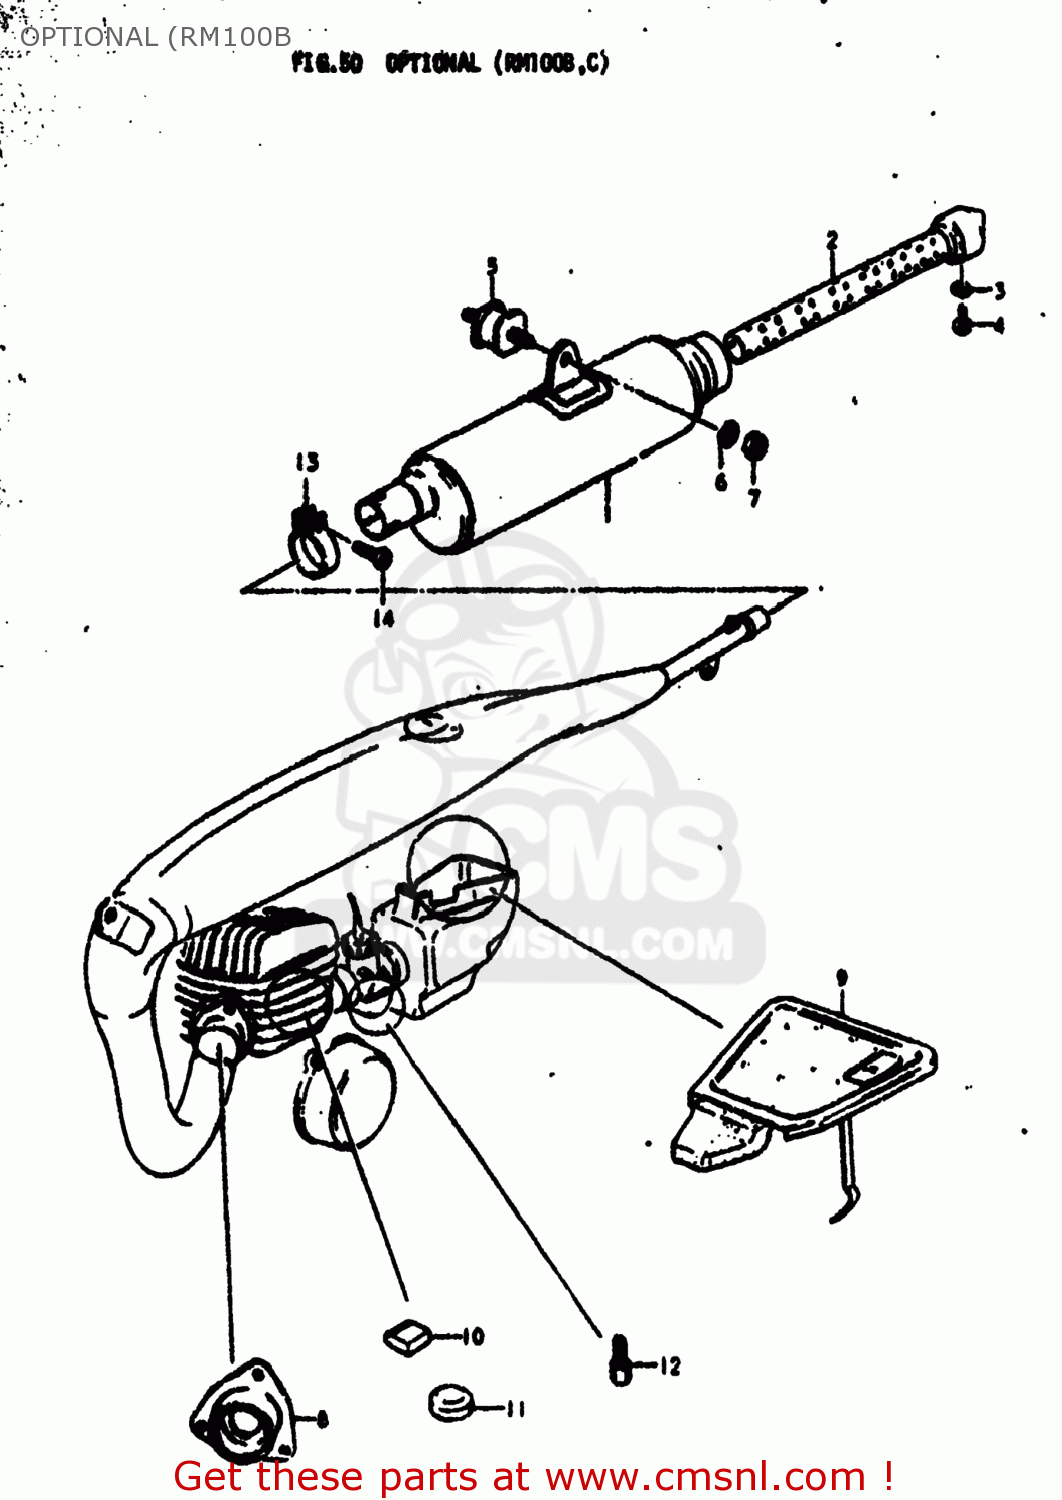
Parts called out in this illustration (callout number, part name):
0	OFF-ROAD SOUND KIT
1	MUFFLER ASSEMBLY
2	PIPE,MUFFLER BAFFLE
3	LOCK WASHER
4	SCREW
5	DAMPER,MUFFLER SUPPORT
6	LOCK WASHER
7	NUT
8	FLANGE,EXHAUST PIPE
9	CAP,AIR CLEANER
10	PAD,CYLINDER
11	PAD,CYLINDER
12	JET
13	CLAMP
14	BOLT(6X20)
